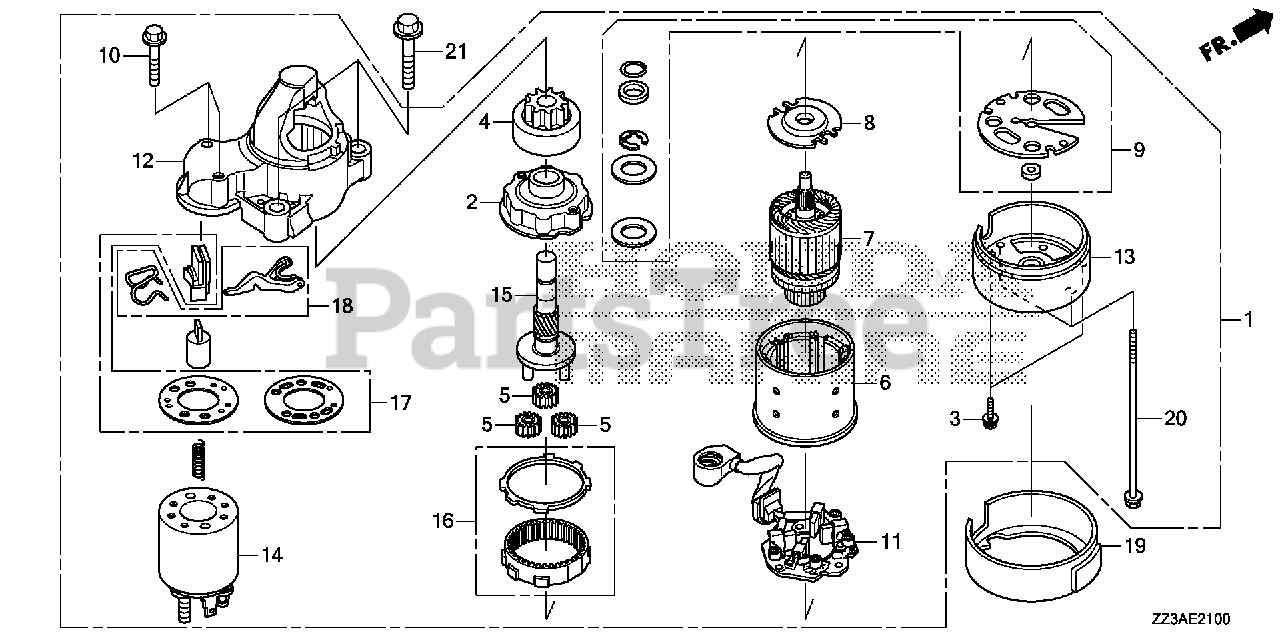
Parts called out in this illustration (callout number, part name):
1	STARTER MOTOR ASSY.
2	BRACKET ASSY., CENTER
3	SCREW (M4X16)
4	PINION ASSY.
5	GEAR, PLANET
6	YOKE ASSY.
7	ARMATURE ASSY.
8	BRACKET, CENTER
9	STOPPER SET, WASHER
10	BOLT (M6X37)
11	HOLDER ASSY., BRUSH
12	CASE ASSY., GEAR
13	COVER ASSY., RR.
14	SWITCH ASSY., MAGNETIC
15	SHAFT, PINION
16	GEAR ASSY. (INNER)
17	COVER KIT, DUST
18	LEVER SET, SHIFT
19	SUSPENSION, STARTER
20	BOLT, THROUGH
21	BOLT, FLANGE (8X45)
